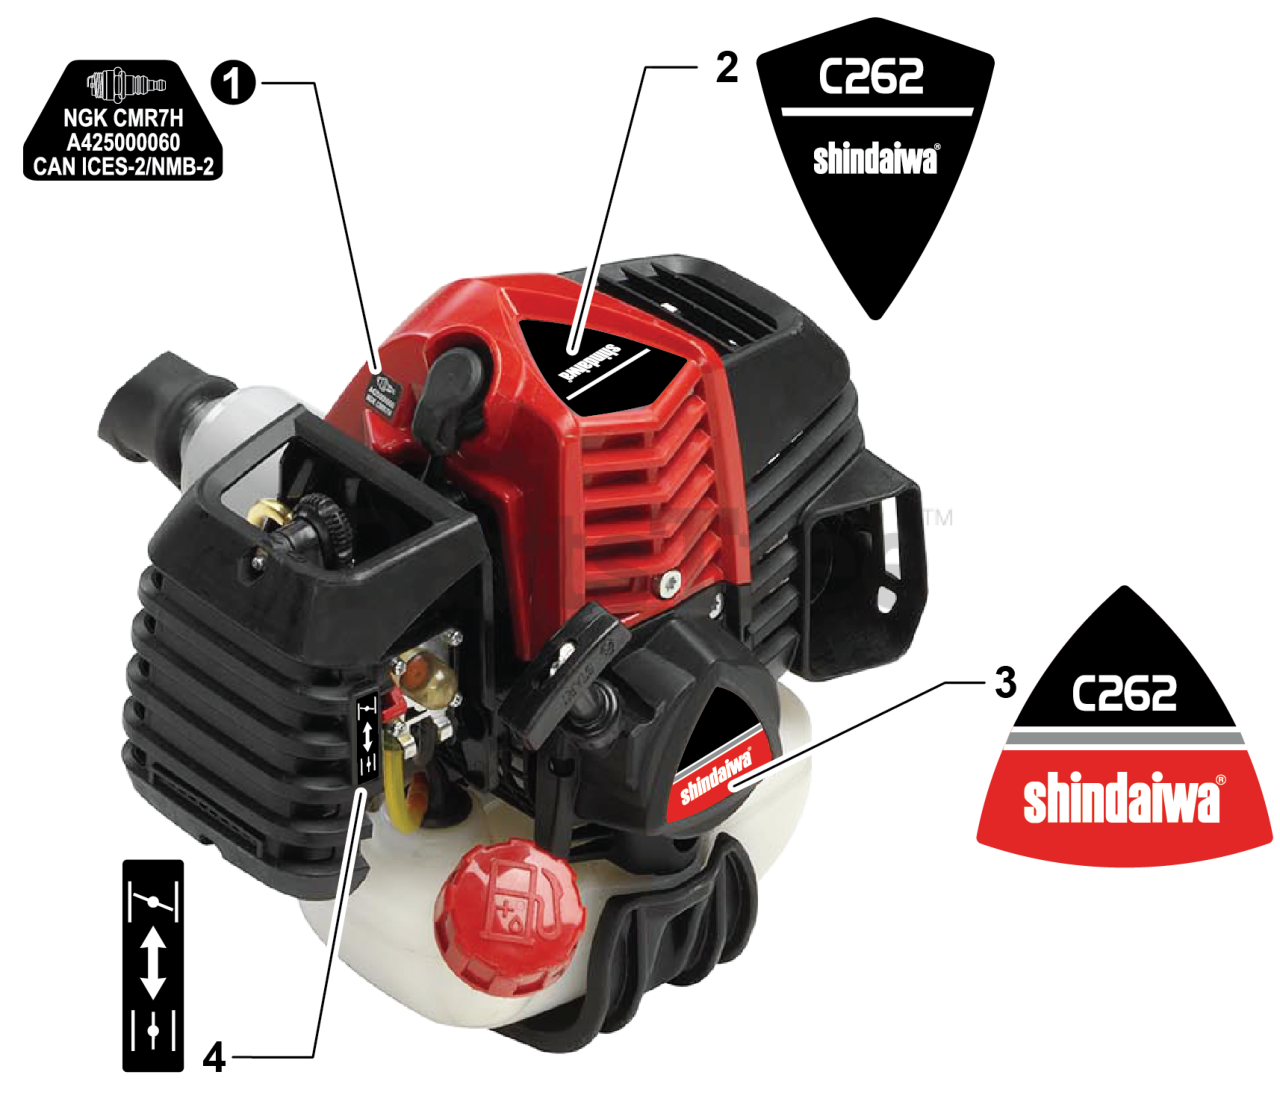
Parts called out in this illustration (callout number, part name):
1	LABEL - SPARK PLUG - CMR7H
2	LABEL - MODEL C262
3	LABEL - RECOIL STARTER
4	LABEL - CHOKE
